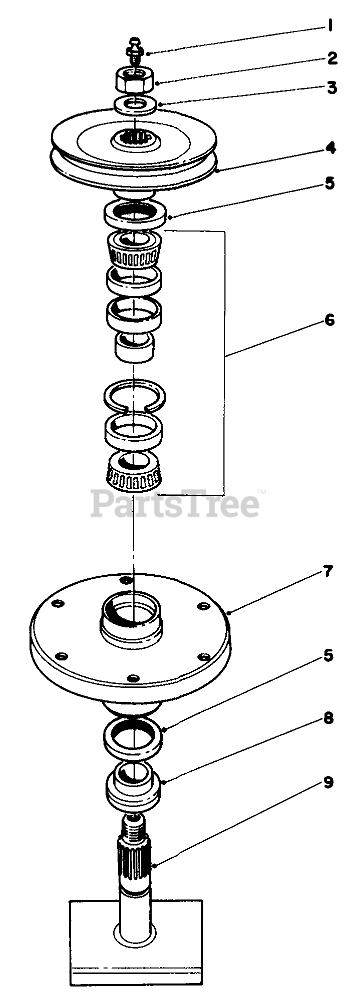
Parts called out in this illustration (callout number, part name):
1	FITTING-GREASE
2	NUT-HEX
3	WASHER
4	PULLEY AND HUB ASM
5	SEAL-OIL
6	BEARING ASM
7	HOUSING-SPINDLE
8	SPACER
9	SHAFT
